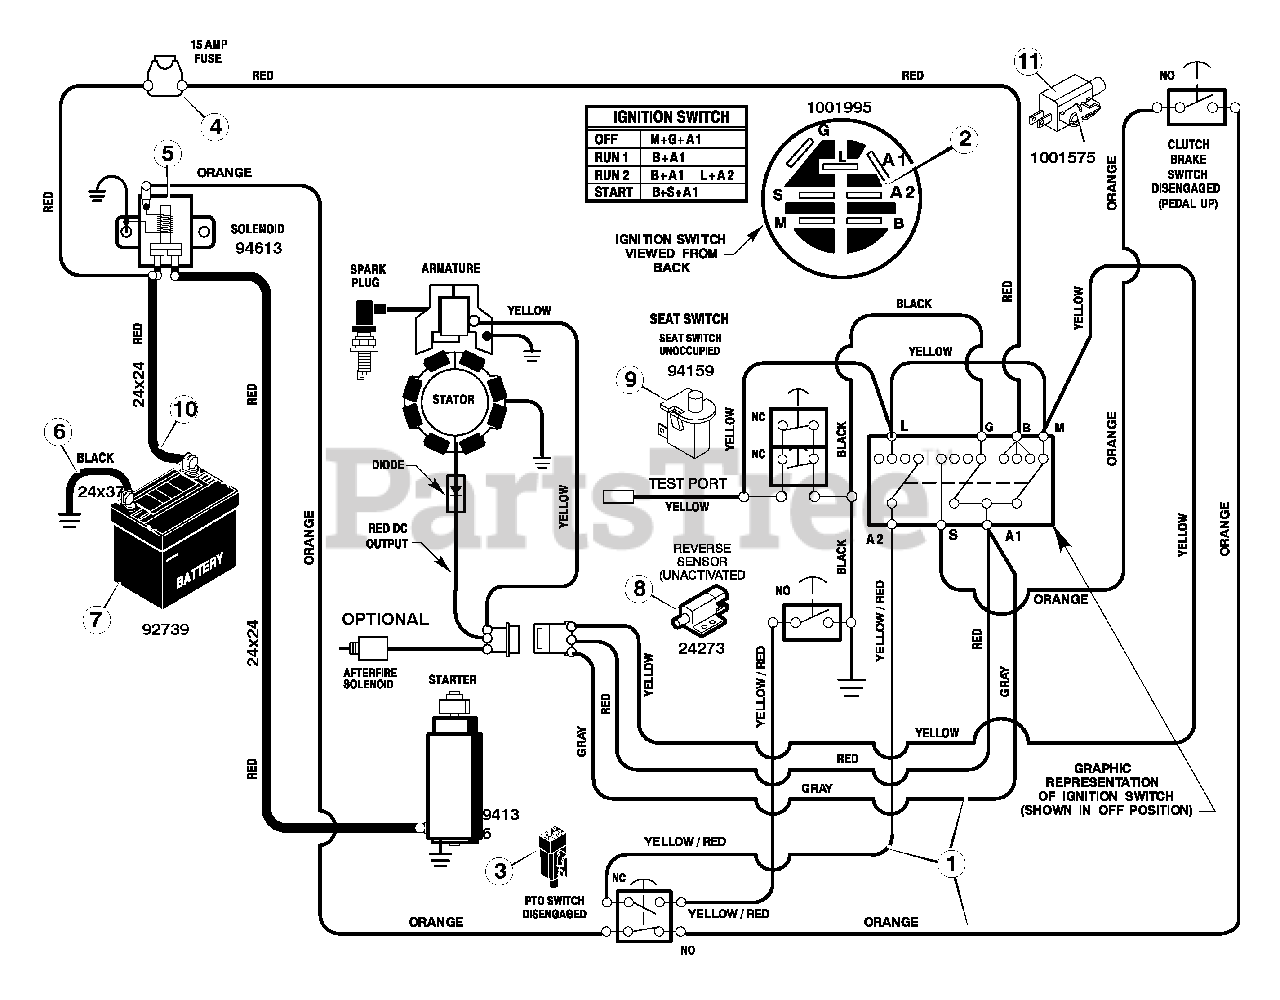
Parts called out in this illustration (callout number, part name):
1	Harness, Chassis Wire
2	Switch, Ignition
3	Switch, Limit (PTO)
5	Solenoid
6	Cable, Battery Ground
7	Battery
8	Switch, Select Reverse3
9	Switch, Seat Sensor
11	Switch, Clutch Brake
